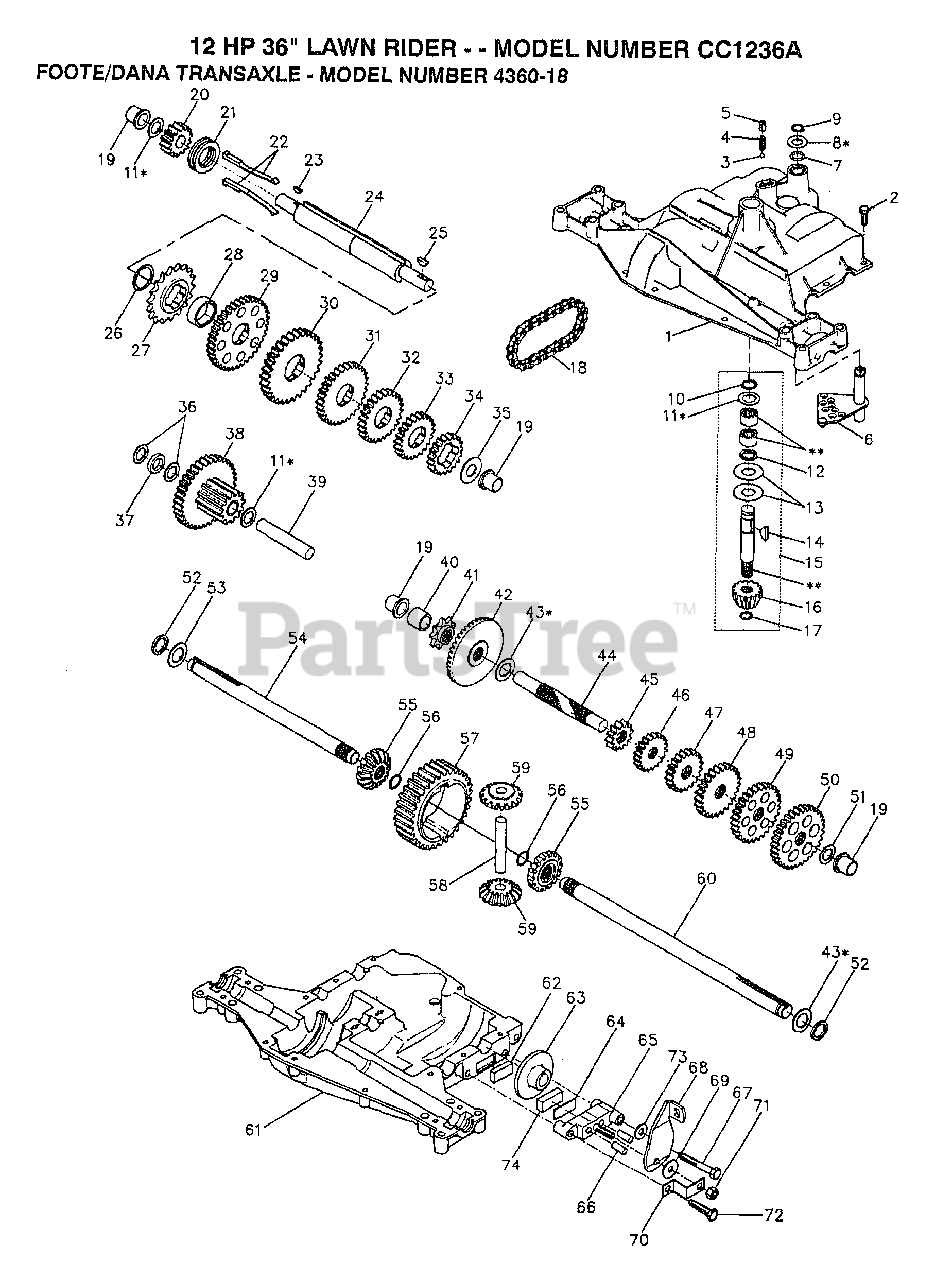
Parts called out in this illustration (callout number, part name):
3	"DETENT, BALL(68003)"
4	"SPRING, DETENT LT"
5	"SCREW, SET LT"
7	ORING T
8	WASHER T
8	PLAIN WASHER
9	RETAINING RING LT
10	RETAINING RING LT
11	WASHER
11	WASHER 020
11	WASHER 025
11	WASHER 031
11	WASHER 035
11	WASHER 040
11	WASHER 045
11	WASHER 050
11	WASHER 060
11	"WASHER, PLAIN LT"
12	O-RING T
13	WASHER T
14	WOODRUFF KEY
15	IMPUT KIT T
16	PINION 14T T
17	"RING,RETAINING LT"
18	"CHAIN,24 PTCH LT"
19	BEARING.FLNG.5510
22	KEY T
25	WOODRUFF KEY
26	"RING,RETAINING LT"
27	SPROCKET 18T T
28	SPACER YT
29	KIT.GEAR.12/37TH
32	GEAR 25T LT
33	GEAR SPUR 22 TT
35	"WASHER, PLAIN LT"
36	WASHER 025
37	SPACER
38	ASSM GEAR COMB
39	SHAFT IDLER T
40	SPACER T
41	SPROCKET 9T LT
43	WASHER LT
43	"WASHER, PLAIN LT"
43	WASHER
43	WASHER 031
43	WASHER PLAIN
43	WASHER 062
44	SHAFT T
48	"GEAR, SPUR 25T LT"
49	GEAR 28T T
50	"GEAR, SPUR 31T LT"
51	WASHER 060
53	WASHER 062
55	GEAR 15T T
56	"RING,RETAINING LT"
58	SHAFT T
59	GEAR 1ST T
62	PUCK T
63	BRAKE DISC. T
64	SPACER LT
66	PIN T
67	SCREW T
68	LEVER ACTUATOR
69	WASHER LT
71	NUT.LOCK.5/16-24
72	"SCREW, TAPPING LT"
73	WASHER T
74	PUCK T
